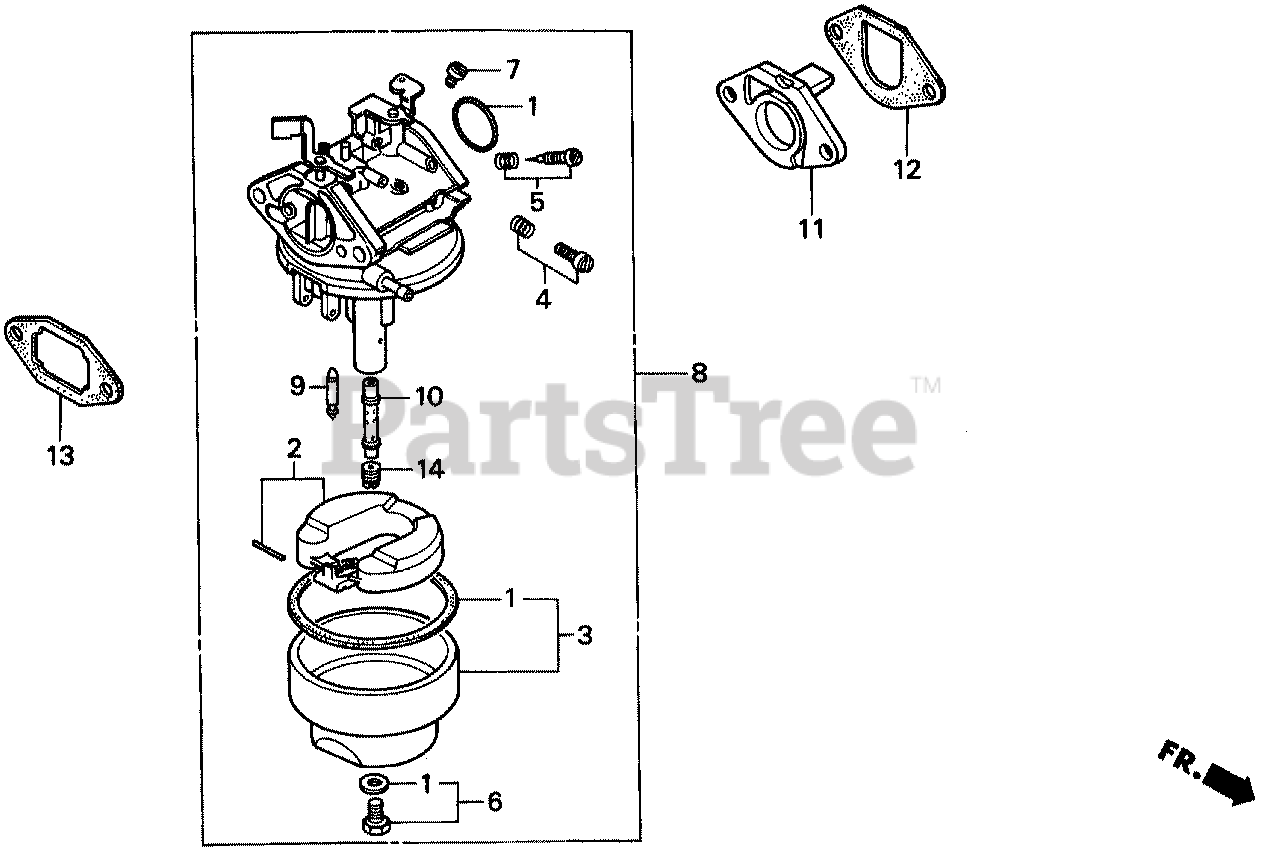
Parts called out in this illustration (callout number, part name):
1	GASKET SET
2	FLOAT SET
3	CHAMBER SET, FLOAT
4	SCREW SET A
5	SCREW SET A
6	SCREW SET B
7	SCREW, PLUG
8	CARBURETOR ASSY.
9	VALVE, FLOAT
10	NOZZLE, MAIN
11	INSULATOR, CARBURETOR
12	GASKET, INSULATOR
13	GASKET, AIR CLEANER
14	JET, MAIN (#45)
14	JET, MAIN (#48)
14	JET, MAIN (#50)
14	JET, MAIN (#52)
14	JET, MAIN (#55)
